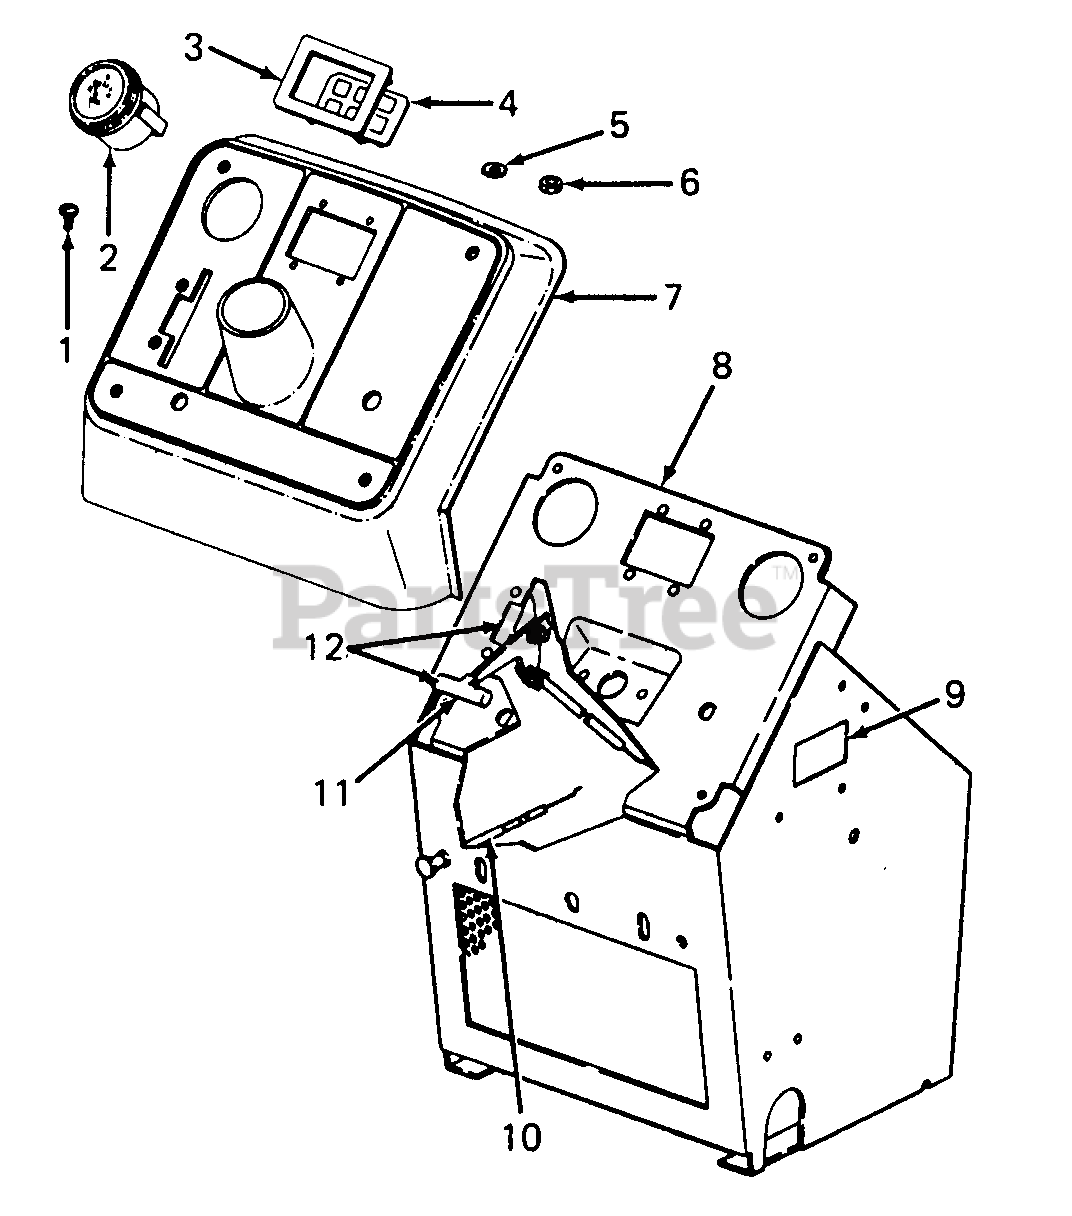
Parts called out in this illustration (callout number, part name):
1	Screw, 10-24 X 3/4 Pan-Hd. Cutting
2	Indicator, Charge
3	Bezel, Light
4	Label, Indicator
5	Washer, .18 X .50 X. 06 Rubber
6	Nut, Self-Threading Pal
7	Panel, Instrument
9	Label, Battery Booster
10	Control, Choke
11	Knob, Throttle Control
12	Control, Throttle
